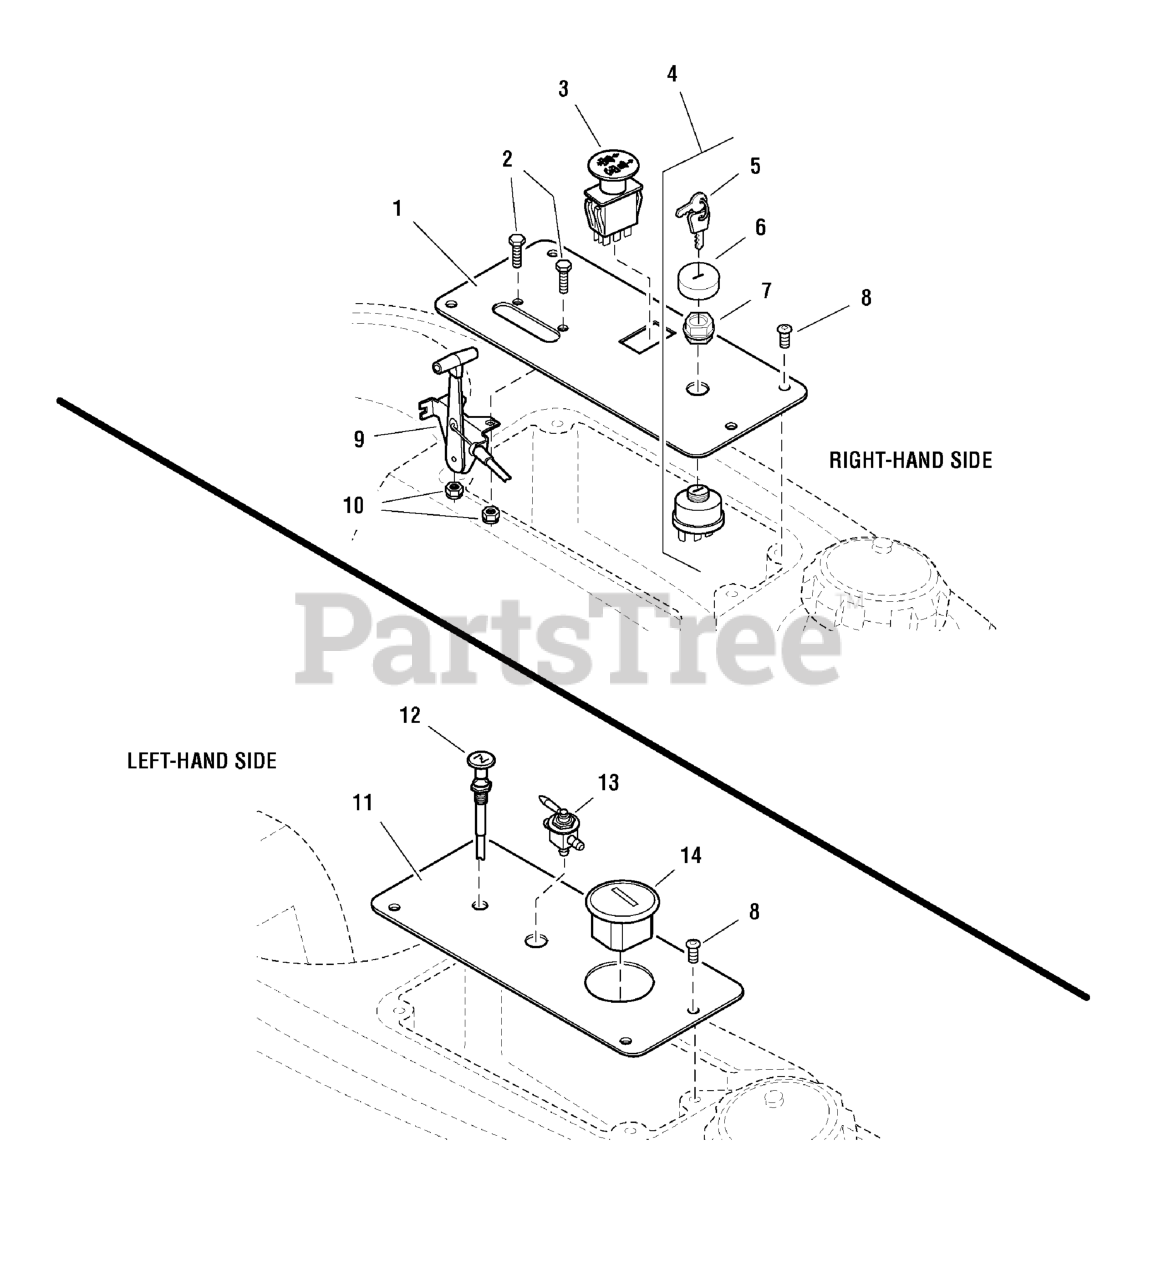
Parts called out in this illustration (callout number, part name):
1	CONTROL PANEL-RH
2	BOLT, 1/4-20 x 3/4
3	SWITCH, BLADE ENGAGEMENT
4	SWITCH, IGNITION, 6 POST
5	KEY, IGNITION MOLDED SET
6	COVER, PLASTIC, SNAP ON
7	PLASTIC NUT
8	SCREW, Allen Head, 1/4-20 x 1/2
9	CABLE, Throttle, 38"
10	NUT, 1/4-20 HEX SERR. FLANGE
11	CONTROL PANEL-LH
12	CABLE, Choke Control
13	VALVE, Fuel Shut Off
14	HOUR METER
